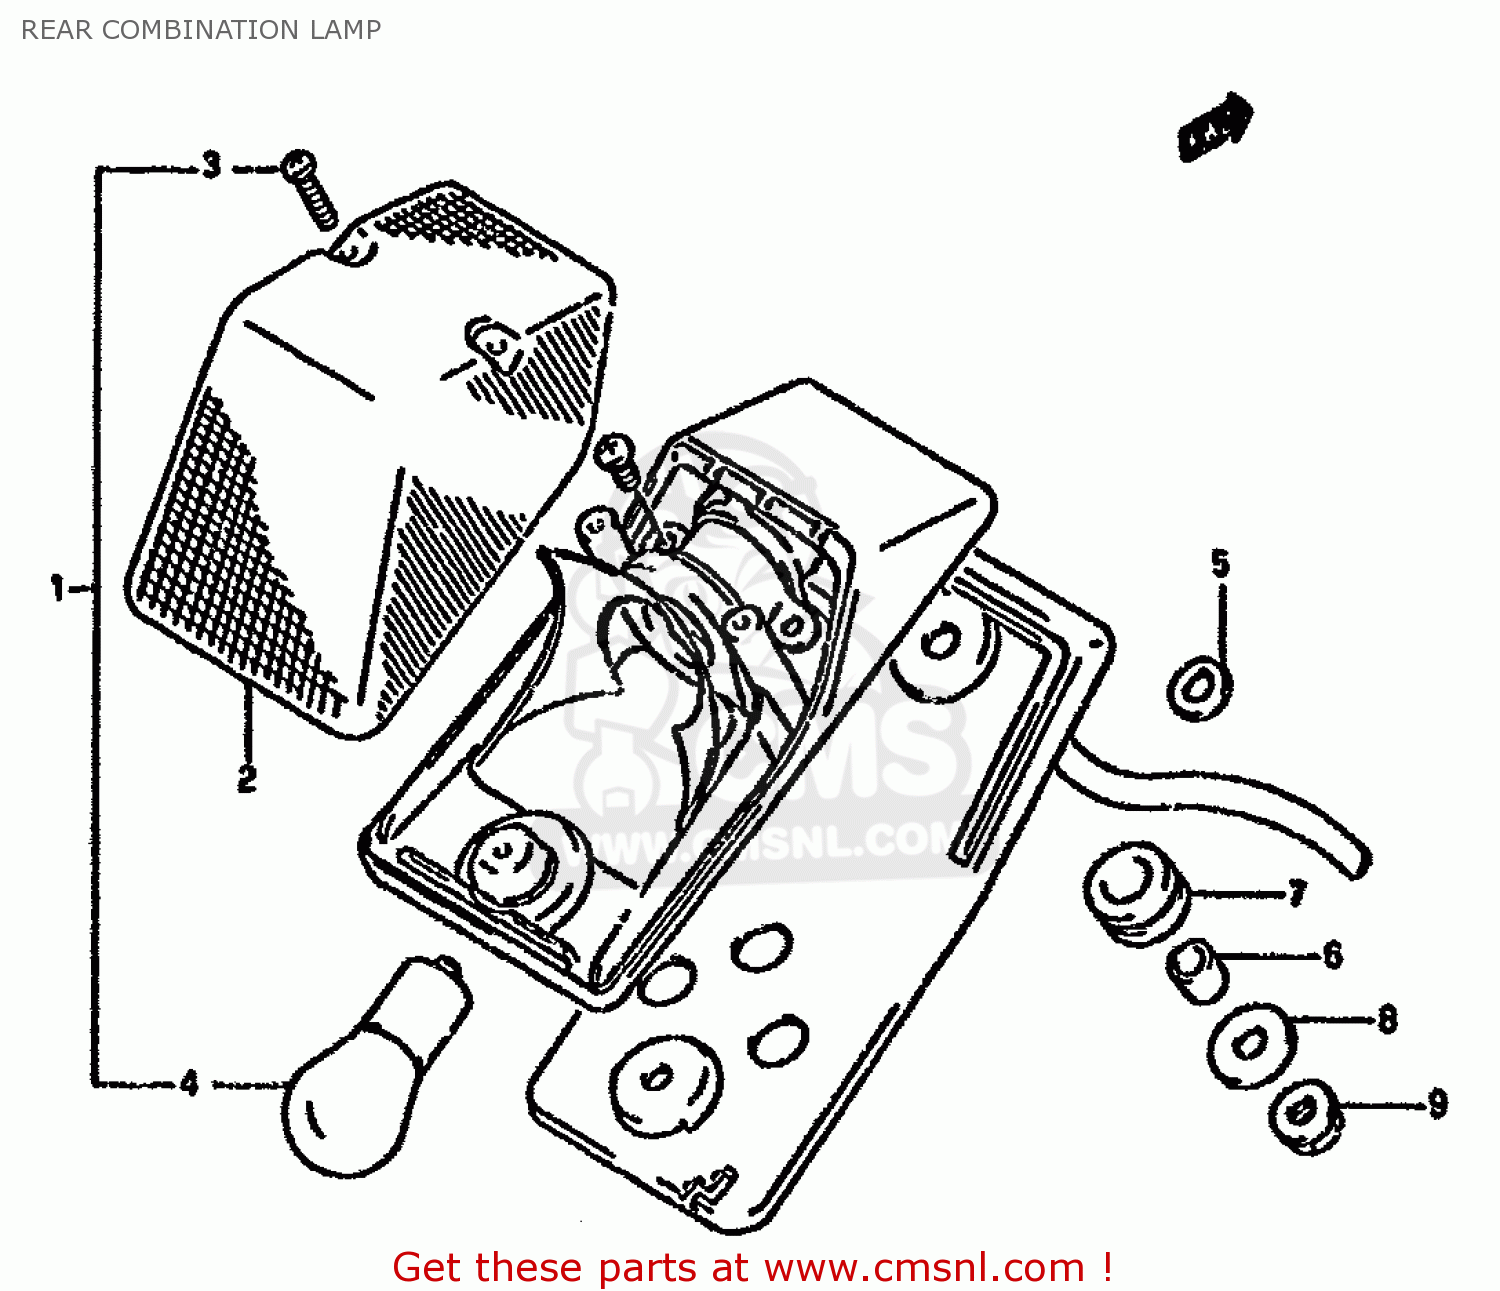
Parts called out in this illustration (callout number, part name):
1	LAMP ASSY,TAIL
2	LENS
3	SCREW
4	BULB(12V5W,BF150-40160A)
5	GASKET (NAS)
6	SPACER(6.3X9.1X11.5)
7	CUSHION
8	WASHER
9	NUT
